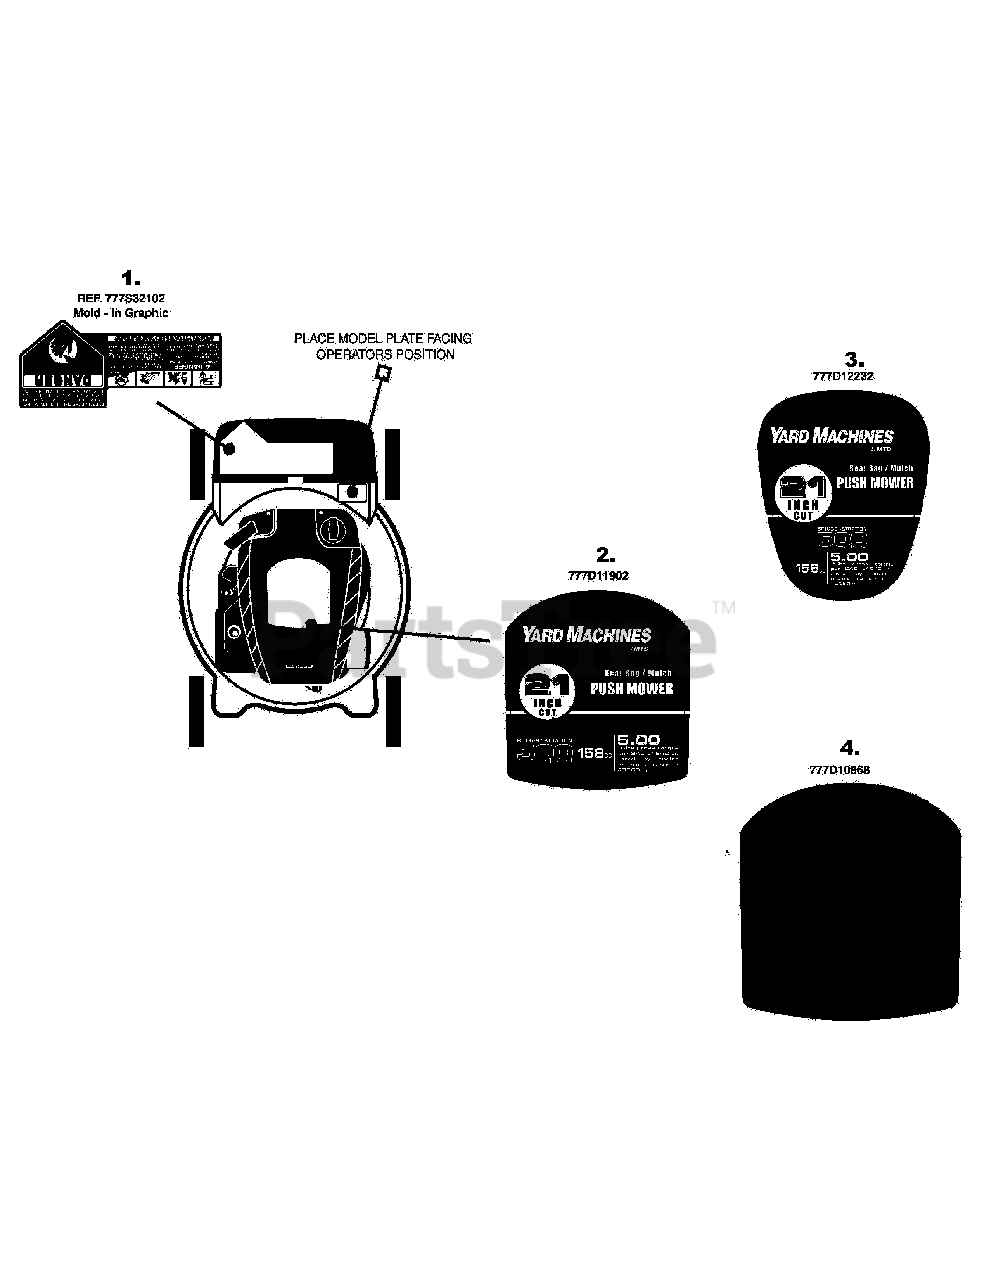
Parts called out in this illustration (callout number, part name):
1	Label
2	LABEL-MOWER SHROUD YARD MACH 21"
3	LABEL-MOWER SHROUD YARD MACH 21"
4	LABEL-MOWER SHROUD:BOLENS
